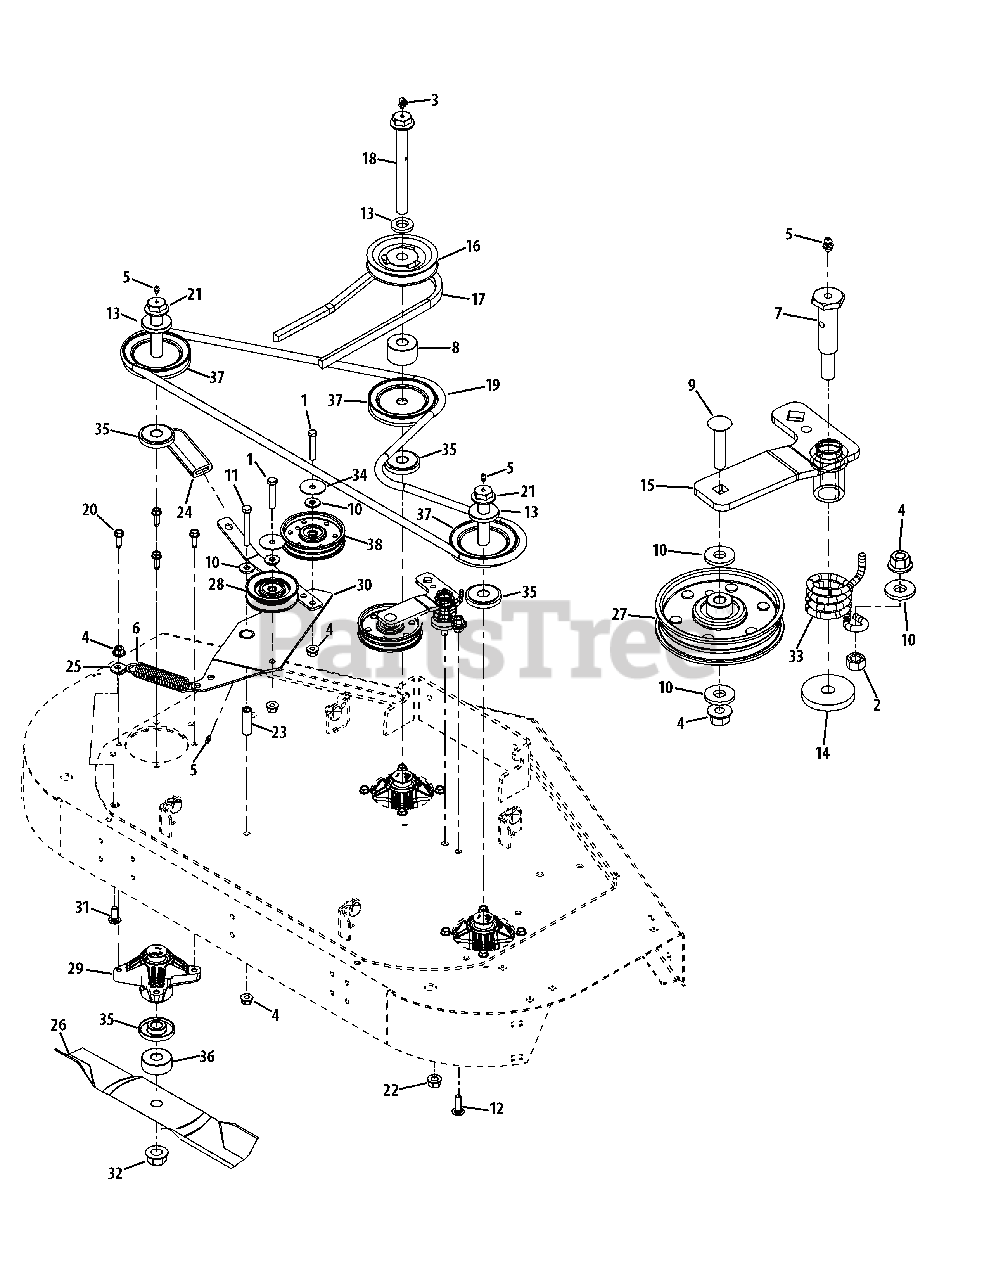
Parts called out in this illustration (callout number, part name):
1	Hex Screw, 3/8-16 x 2.00
2	Nut, 3/8-16
3	Grease Fitting, 1/4-28 x .788
4	Flange Counter Lock Nut, 3/8-16
5	Grease Fitting, 1/4-28
6	Extension Spring, 1.00 x 5.00 x .125
7	Shoulder Bolt, .625 x 1.95
8	Spacer, .760 x 2.00 x 1.27
9	Carriage Bolt, 3/8-18 x 1.75
10	Washer, .406 x 1.00 x .105
11	Hex Screw, 3/8-16 x 3.00
12	Carriage Bolt, 3/8-16 x 1.25
13	Spacer, 2.0 x .75 ID x .31
14	Washer, .438 x 1.75 x .250
15	Idler Arm Assembly
16	Pulley
17	V-Belt, PTO
18	Hex Bolt, 3/4-16 x 7.7"
19	V-Belt, Deck
20	Hex Flange Screw, 5/16-18 x 1.00
21	Hex Flange Bolt, 3/4-16 x 5.85"
22	Flange Counter Lock Nut, 7/16-14
23	Spacer, .390 x .625 x 1.88
24	Flat Grip, 1.0 x 3.2 x .25
25	Spring Mount Bracket
26	Hi-Lift Blade, 17.0
27	Idler Pulley
28	Idler Pulley
29	Spindle Assembly
30	Double Idler
31	Carriage Bolt, 3/8-16 x 1.00
32	Flange Lock Nut, 3/4-16
33	Torsion Spring
34	Washer, .406 x 1.92 x .060
35	Deck Spindle Spacer
36	Spacer, .760 x 2.000 x .790
37	Pulley
38	Idler Pulley
